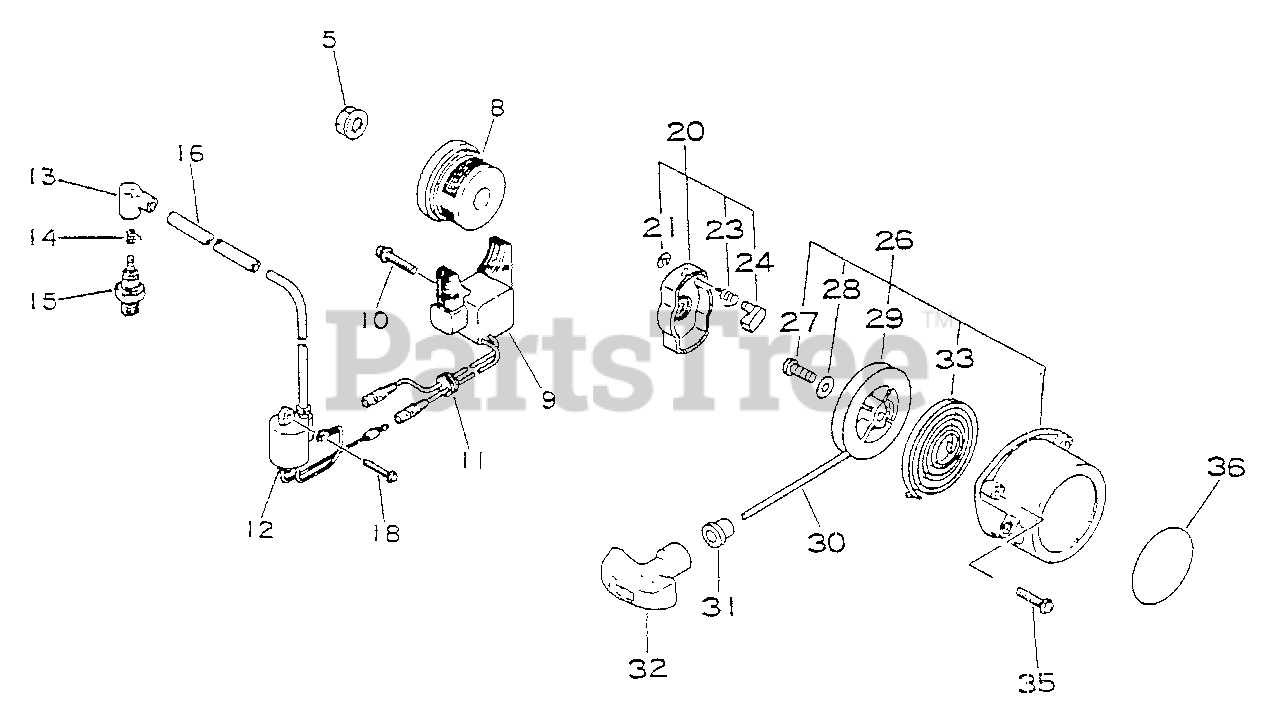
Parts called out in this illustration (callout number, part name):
5	NUT, FLANGE 10×1.25
8	FLYWHEEL
9	COIL, IGNITION
10	SCREW 5×25
12	COIL, IGNITION
13	CAP, SPARK PLUG
14	TERMINAL, SPARK PLUG CAP
15	SPARK PLUG - BM6A
16	TUBE, INSULATOR
18	SCREW 4×25
20	PAWL CATCHER ASSY
21	E-RING 4
23	SPRING, RETURN
24	PAWL, STARTER
26	STARTER ASSY
29	REEL, ROPE
30	ROPE, STARTER 4.0×880
31	GUIDE, ROPE
32	GRIP, STARTER
33	SPRING, RECOIL
35	SCREW 5×16
36	LABEL, ECHO
